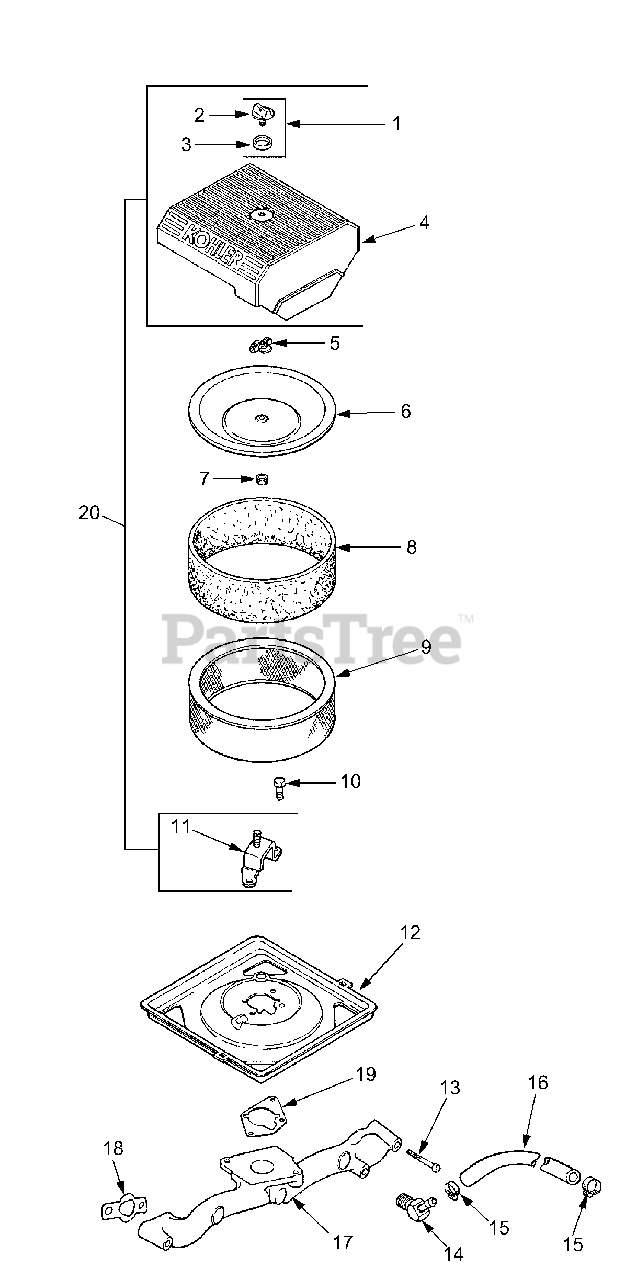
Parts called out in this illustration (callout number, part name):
1	Kit, Knob w/Seal
3	Seal, Air Cleaner Cover Knob
4	Cover, Air Cleaner
6	Cover, Inner Air Cleaner
7	Seal, Inner Air Cleaner
8	Precleaner, Element
9	Element, Air Cleaner
10	Screw, Hex Flange M6 x 1.0 x 16
11	Bracket, Air Cleaner Base
12	Base, Air Cleaner
13	Screw, Hex Flange M6 x 1.0 x 55
14	Connector, Hose 45°.
15	Clamp, Hose
16	Line, Fuel 17"
17	Manifold, Intake
18	Gasket, Intake Manifold
19	Gasket, Air Cleaner Base
20	Kit, Air Cleaner Cover
